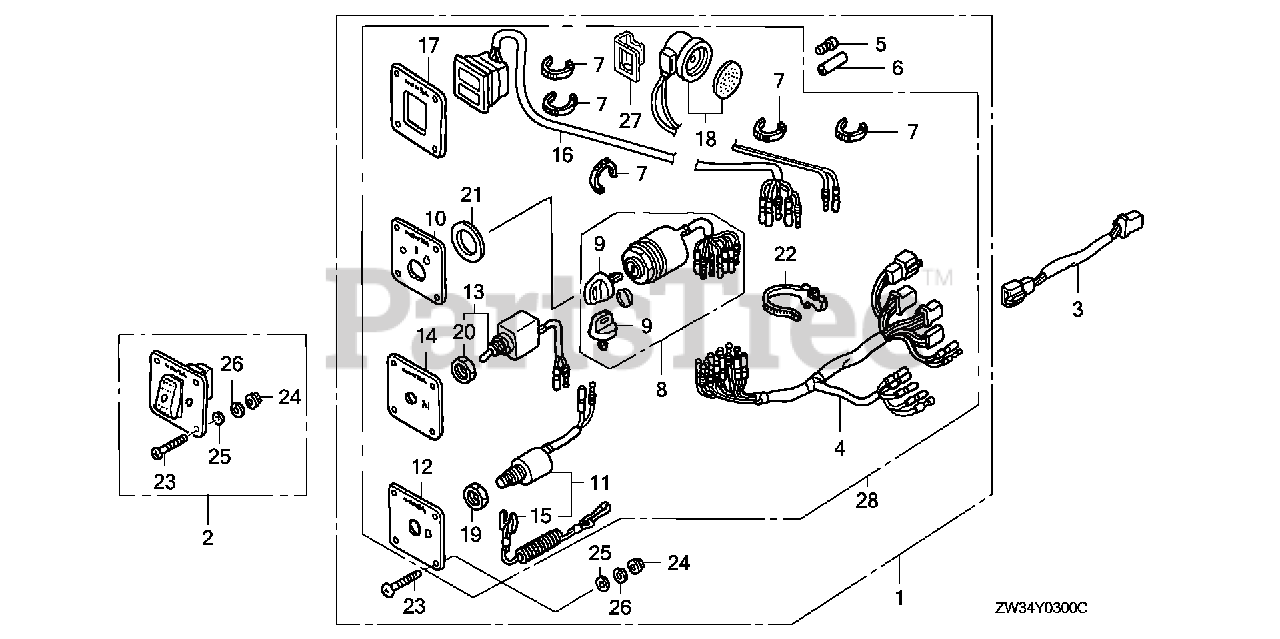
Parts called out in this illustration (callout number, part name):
1	PANEL KIT, CONTROL (2-LED) (A)
2	SWITCH KIT, LIGHT
3	SUB-HARNESS ASSY., POWER TRIM-TILT (A)
4	HARNESS ASSY., SWITCH PANEL
5	PLUG, CONNECTOR (INNER) (TROLLING CONTROL)
6	PLUG, CONNECTOR (OUTER) (ENGINE NO.)
7	TIE, CABLE (NATURAL 2.4X92) Use up to Frame SN 1300359.
8	SWITCH ASSY., COMBINATION DUAL QTY = (2) (SINGLE)
9	KEY ASSY., COMBINATION SWITCH (35100-ZV5-003 ONLY) DUAL QTY = (4) (SINGLE)
10	PANEL, SWITCH
11	SWITCH ASSY., EMERGENCY STOP
12	PANEL, EMERGENCY STOP SWITCH
13	SWITCH ASSY., SOLENOID
14	PANEL, SOLENOID
15	WIRE, EMERGENCY (SINGLE) (DUAL)
16	LAMP ASSY., INDICATOR (2-LED)
17	PANEL, INDICATOR
18	BUZZER, WARNING
19	NUT, HEX. (16MM) DUAL QTY = (2) (SINGLE)
20	NUT, HEX. (12MM)
21	WASHER, PLAIN
22	BAND, WIRE HARNESS (150MM) (NATURAL) DUAL QTY = (2) (SINGLE)
23	SCREW, PAN (5X40) DUAL QTY = (8) (SINGLE)
24	NUT, FLANGE (5MM) DUAL QTY = (8) (SINGLE)
25	WASHER, PLAIN (5MM) DUAL QTY = (8) (SINGLE)
26	WASHER, SPRING (5MM) DUAL QTY = (8) (SINGLE)
27	BRACKET, BUZZER
